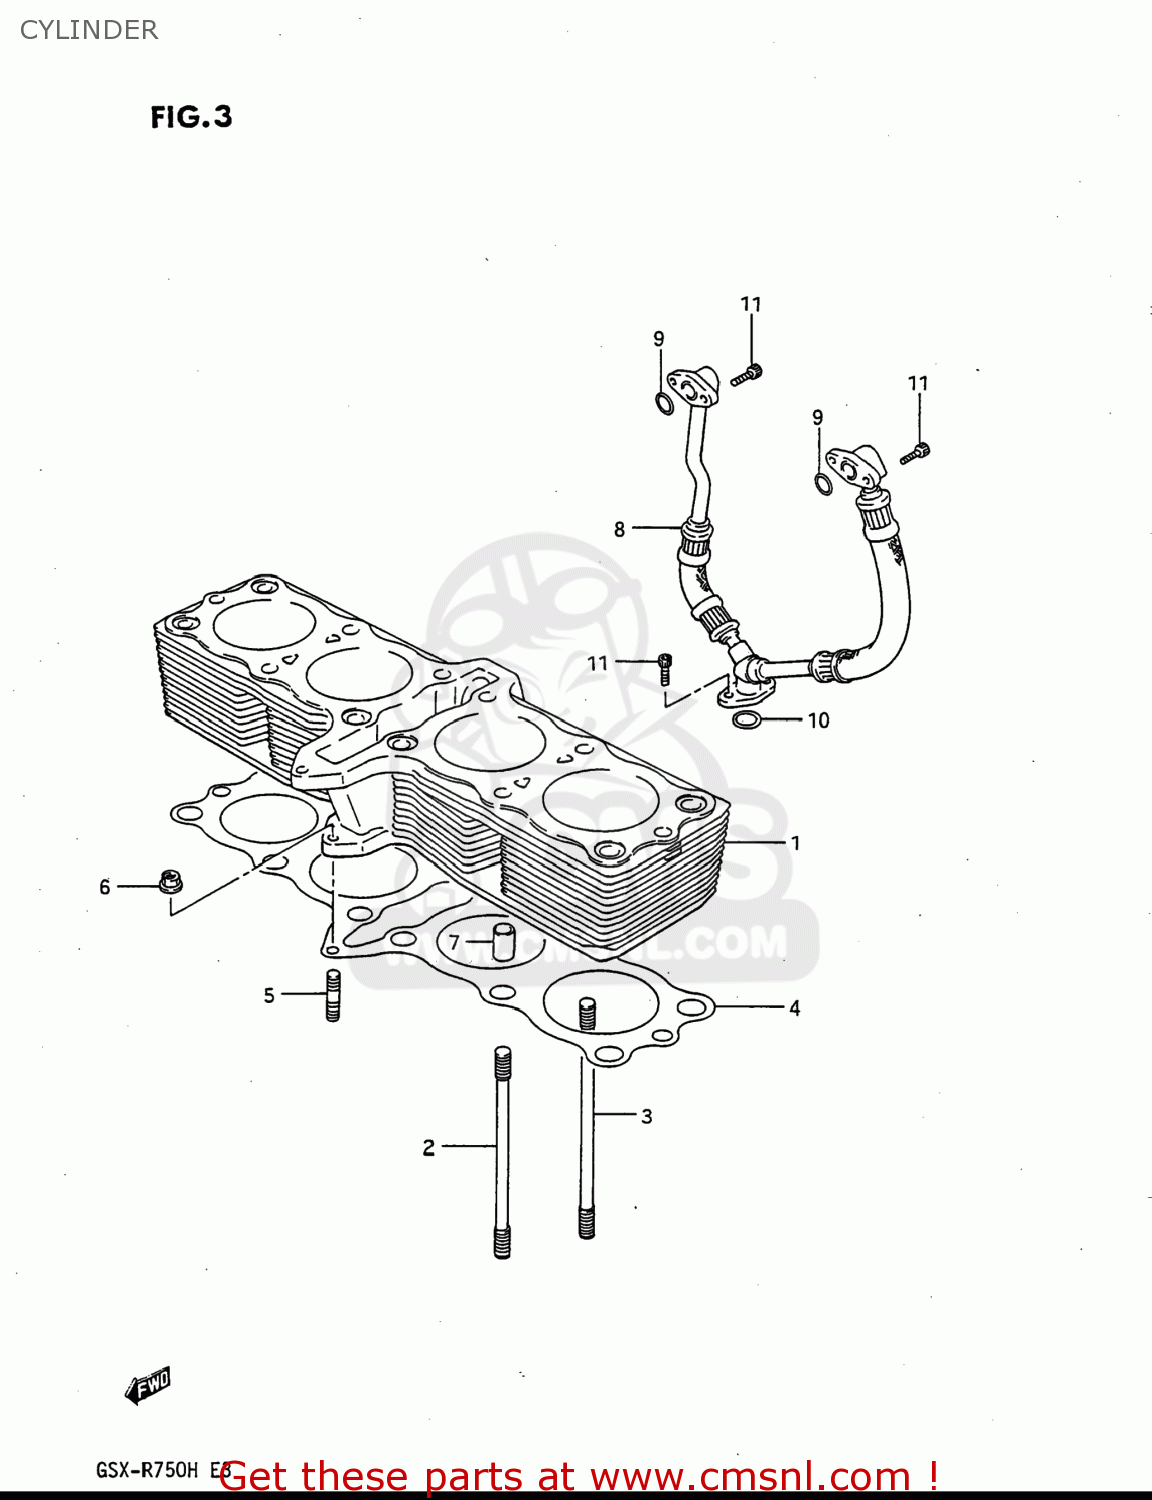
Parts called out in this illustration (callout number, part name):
1	CYLINDER
2	STUD
3	BOLT,STUD
4	GASKET,CYLINDER (NAS)
5	STUD BOLT L:20
6	NUT 6MM
7	PIN
8	HOSE
9	O RING(D:2.5,ID:13.8)
10	O RING(D:2.4,ID:15.8)
11	BOLT
